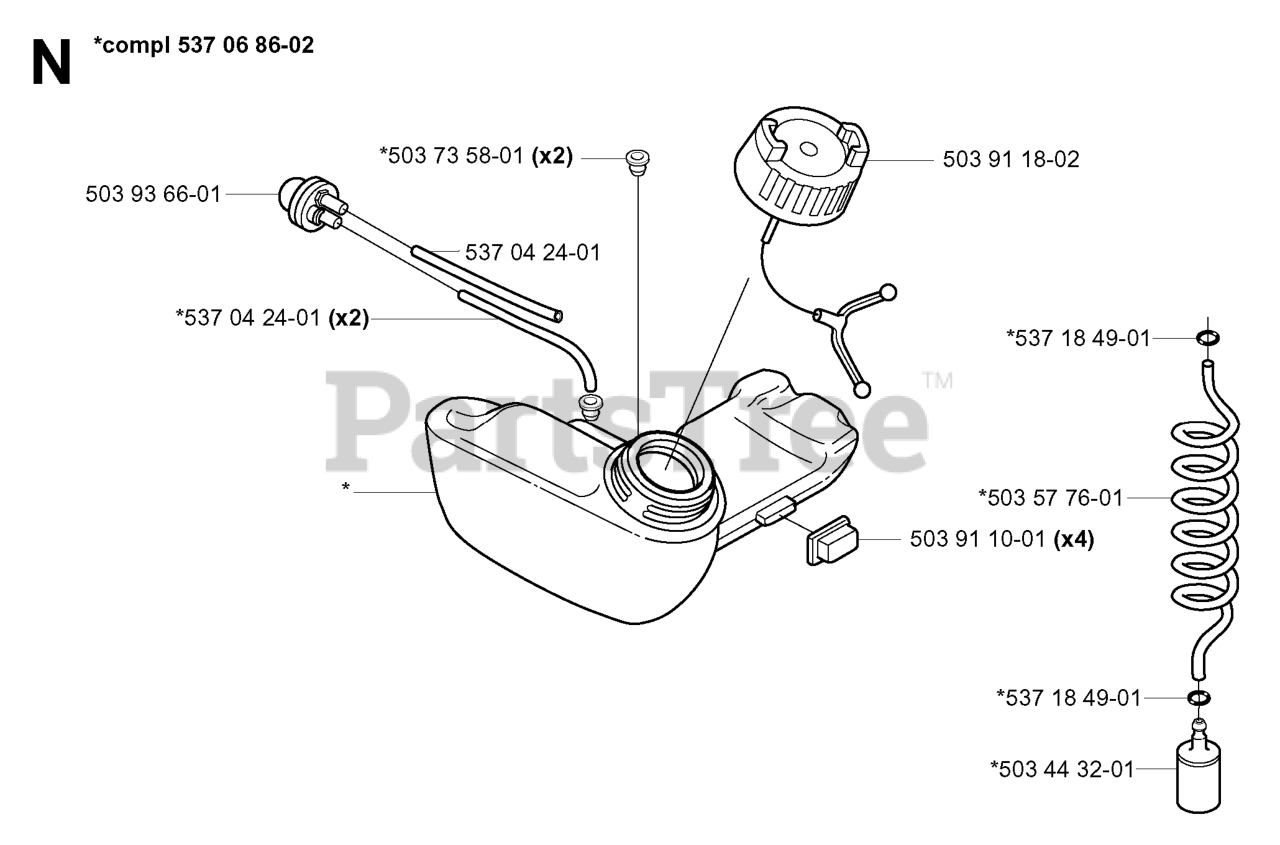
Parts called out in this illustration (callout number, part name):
1	SPRING.INTERLOCK
2	CAM.INTERLOCK.RELEASE
3	SPRING.TORSION.LEVER
4	SPRING RETAINER
5	SCREW 14-20 X 5/8
6	STOP.INTERTLOCK
